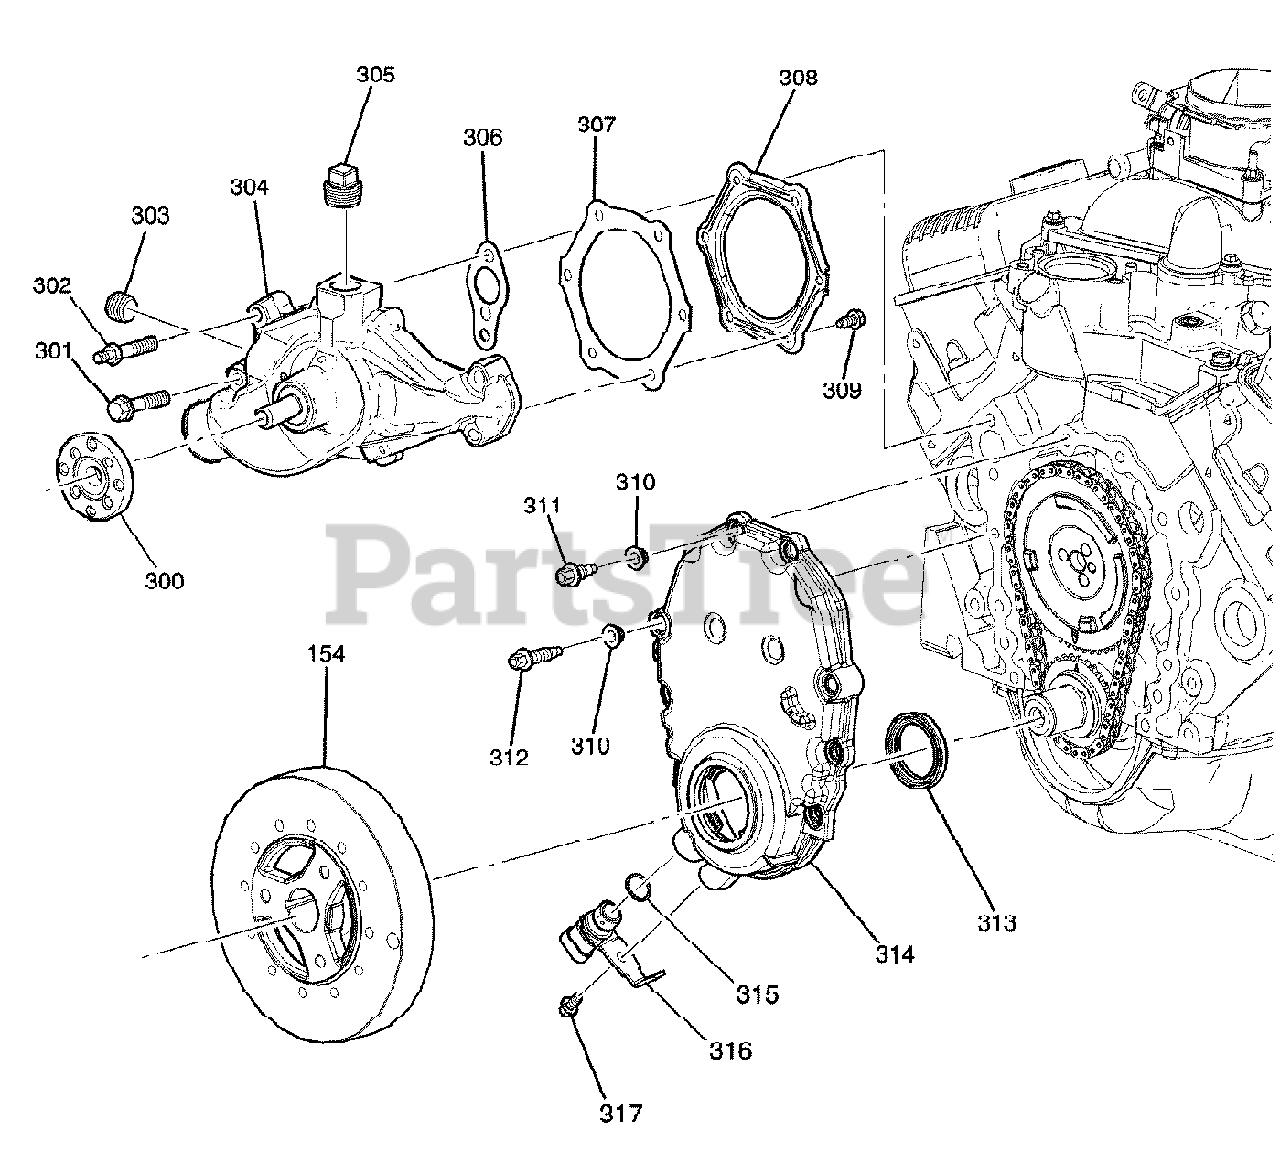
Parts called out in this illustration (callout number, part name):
154	* CRANKSHAFT BALANCER
300	* HUB
302	* STUD
303	* PLUG
304	WATER PUMP WITH GASKET
305	* PLUG
306	WATER PUMP GASKET
307	* GASKET
308	* COVER
311	* BOLT
312	* BOLT
313	* SEAL
314	* COVER
315	* SEAL
316	* SENSOR
317	* BOLT
